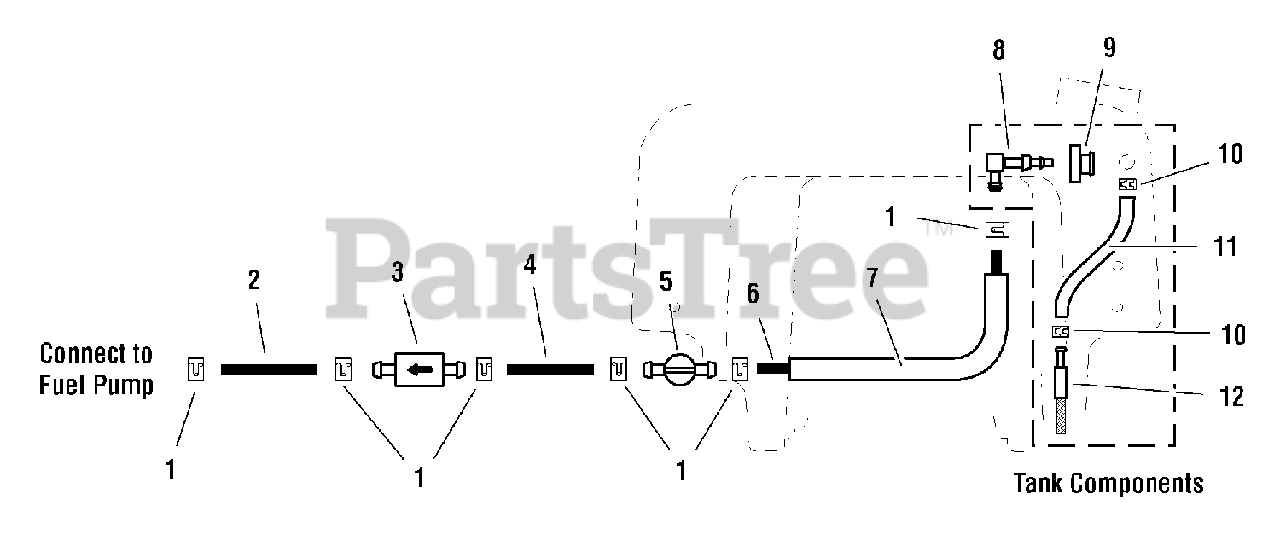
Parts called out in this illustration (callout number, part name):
1	CLAMP, Hose
2	HOSE, 5" (supplied with engine)
5	VALVE, FUel Shut-Off
6	HOSE, 15"
7	WIRE LOOM, 13"
8	ELBOW FITTING
10	HOSE CLAMP
11	HOSE, 20"
12	SCREEN FITTING
